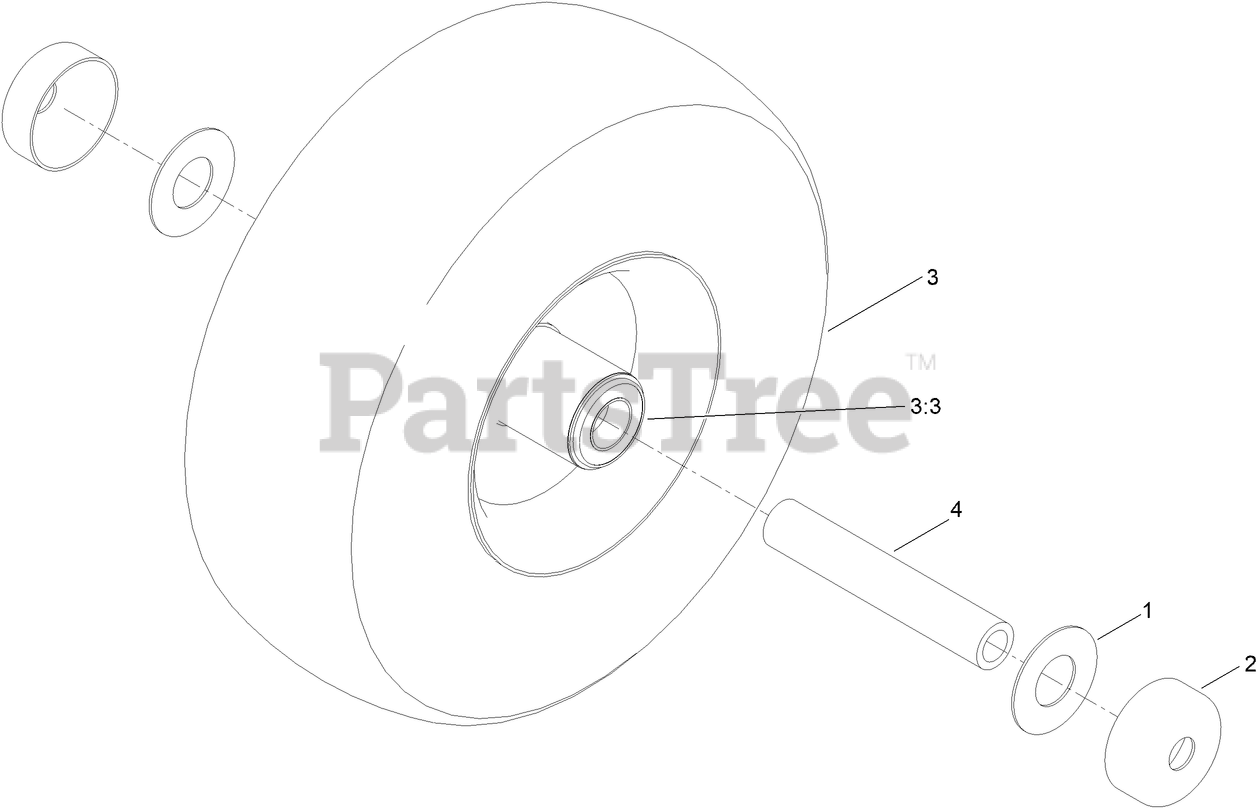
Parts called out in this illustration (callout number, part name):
1	WASHER
2	GUARD-SEAL
3	TIRE AND WHEEL ASM
3:3	BEARING
4	BUSHING-SPANNER
